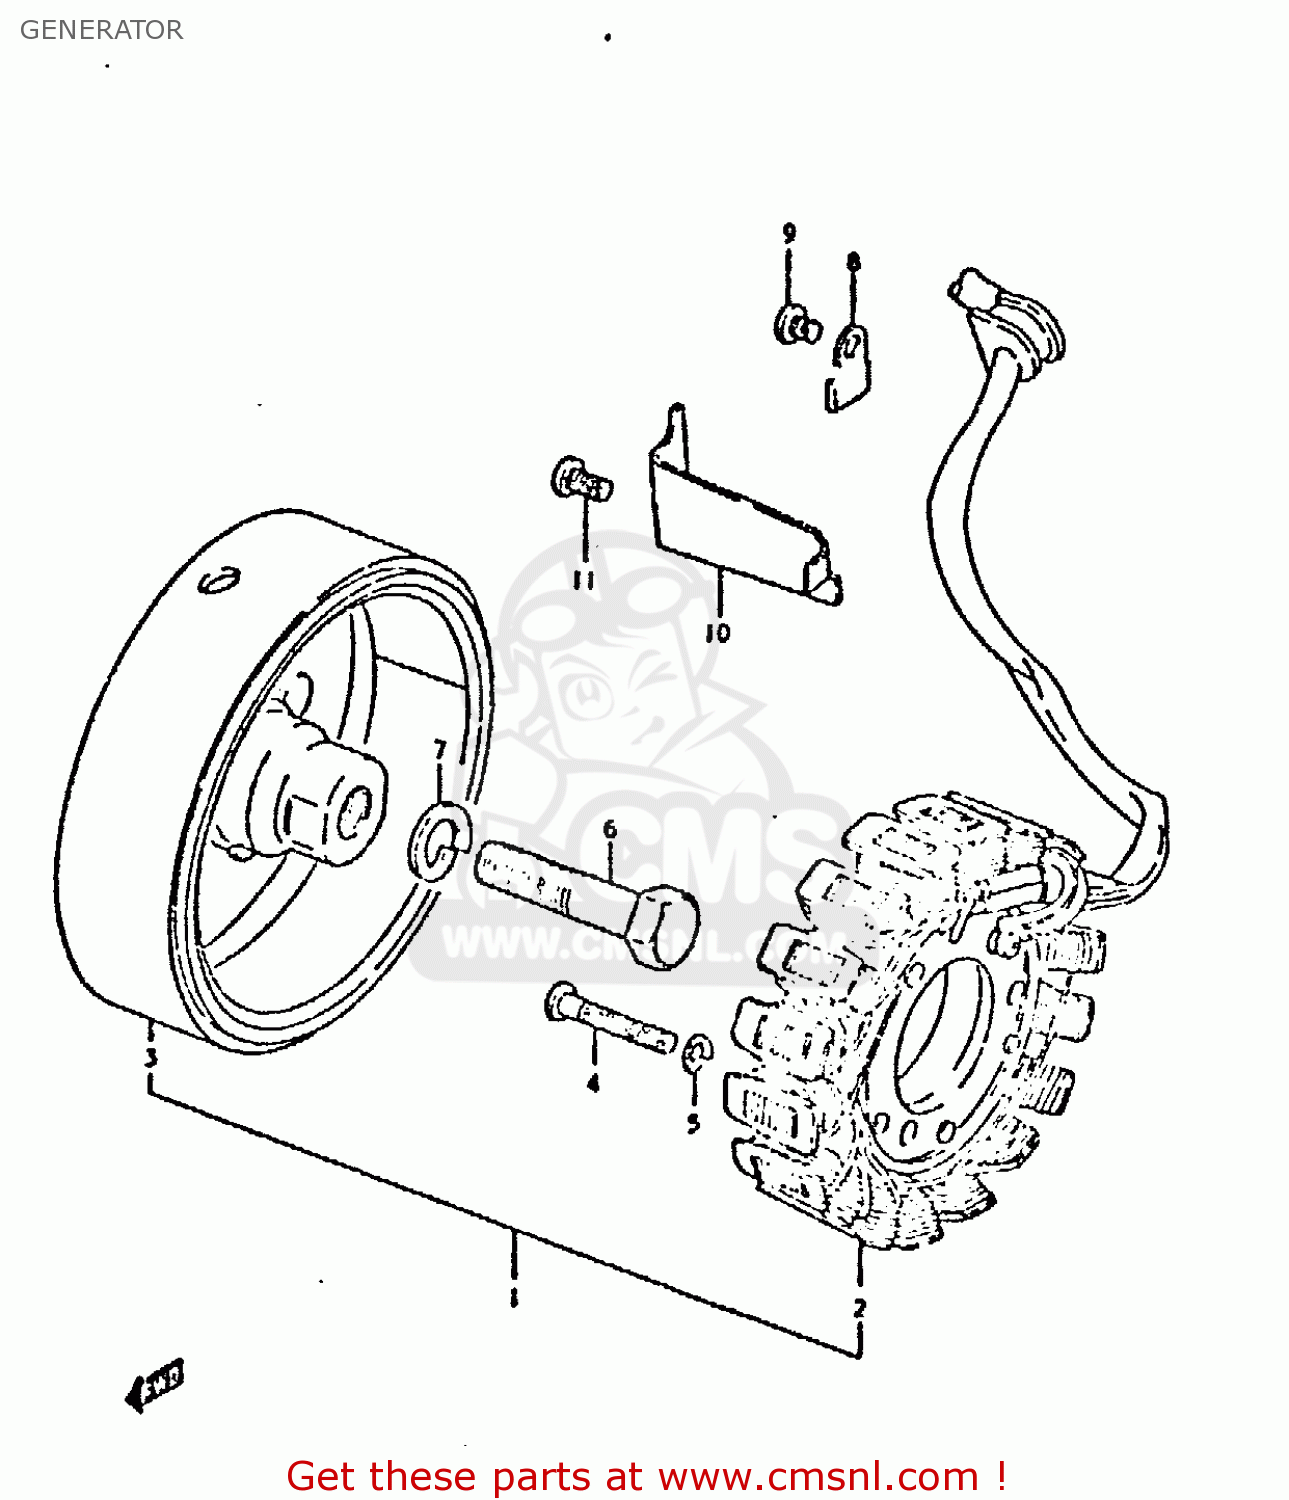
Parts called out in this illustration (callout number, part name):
1	GENERATOR ASSEMBLY
2	STATOR ASSEMBLY
3	ROTOR ASSEMBLY
4	SCREW
5	LOCK WASHER
6	BOLT 12X45
7	WASHER,LOCK 12
8	CLAMP,GENERATOR LEAD WIRE
9	SCREW
10	CLAMP,GENERATOR LEAD WIRE
11	SCREW
